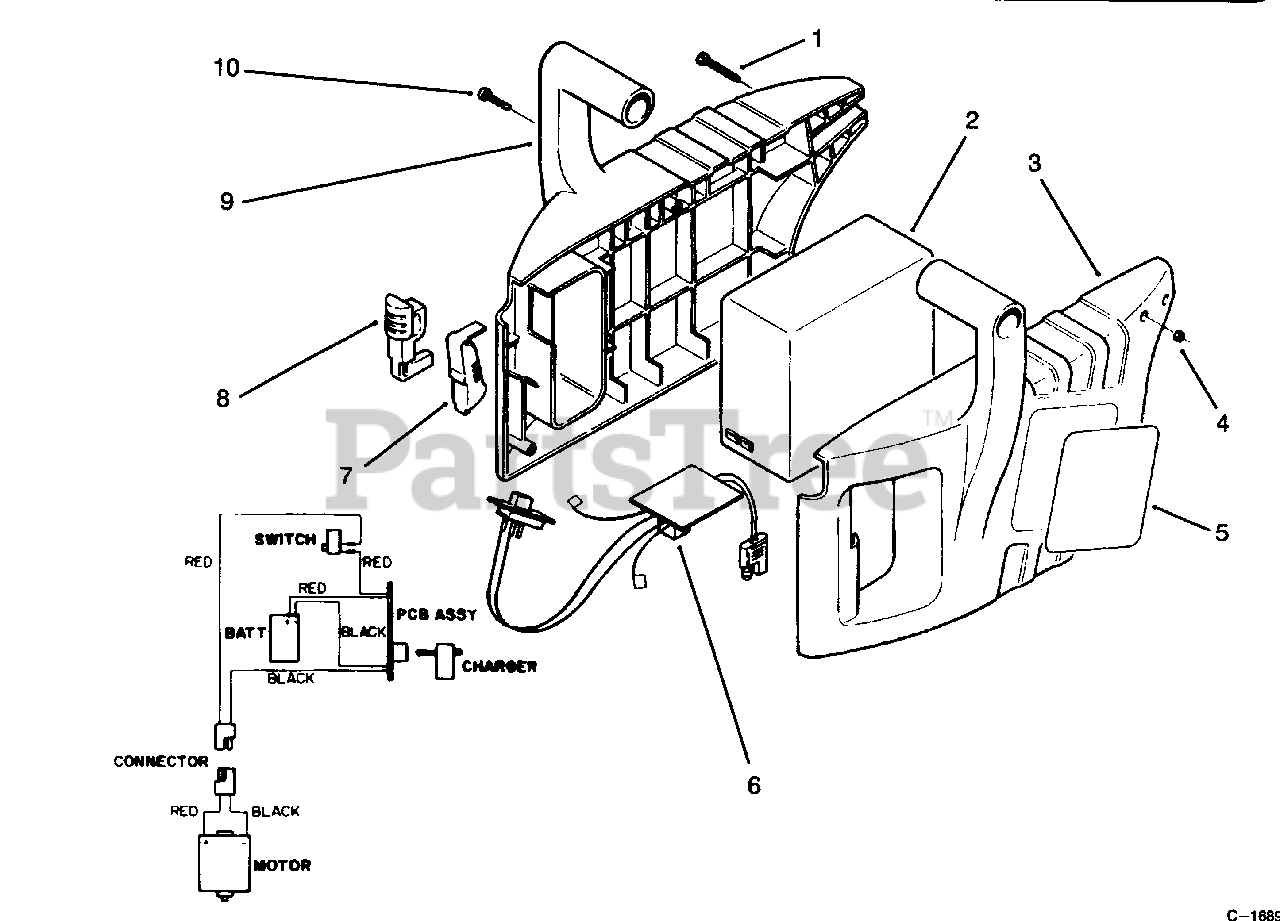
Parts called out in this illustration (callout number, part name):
1	Screw-Self Tapping
3	Handle & Battery Case R.H.
5	Decal-Toro
6	Wiring Harness
8	Lock-Trigger
9	Handle & Battery Case L.H.
10	Screw
